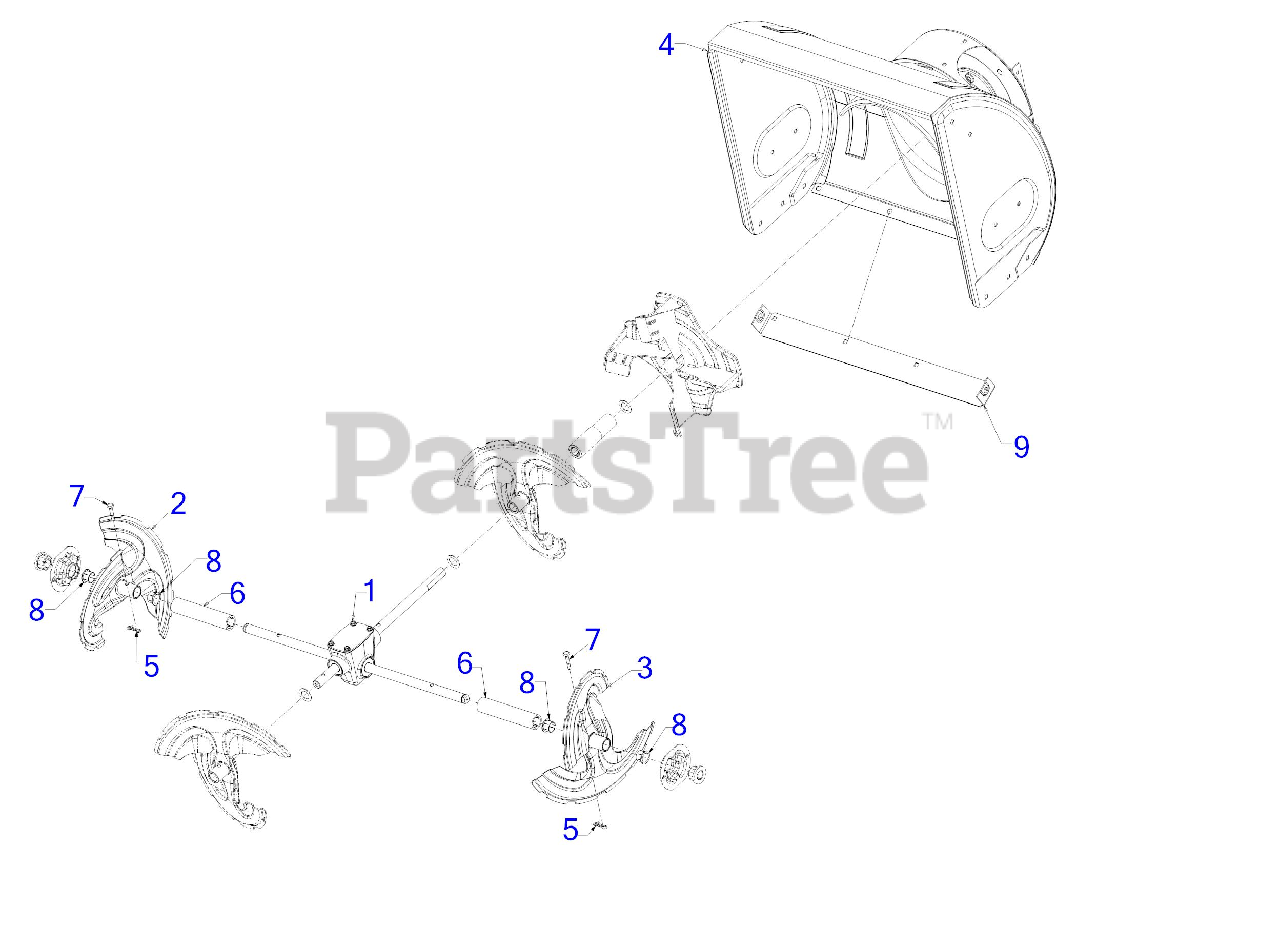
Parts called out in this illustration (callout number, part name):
1	24" AUGER GEARBOX ASSEMBLY
2	SPIRAL ASSEMBLY (RH)
3	SPIRAL ASSEMBLY (LH)
4	24" AUGER HOUSING ASSEMBLY
5	BOW TIE COTTER PIN 1/4-5/16
6	SPACER
7	SHEAR PIN .25 x 1.50 GR2
8	FLANGE BUSHING
9	24" SHAVE PLATE
